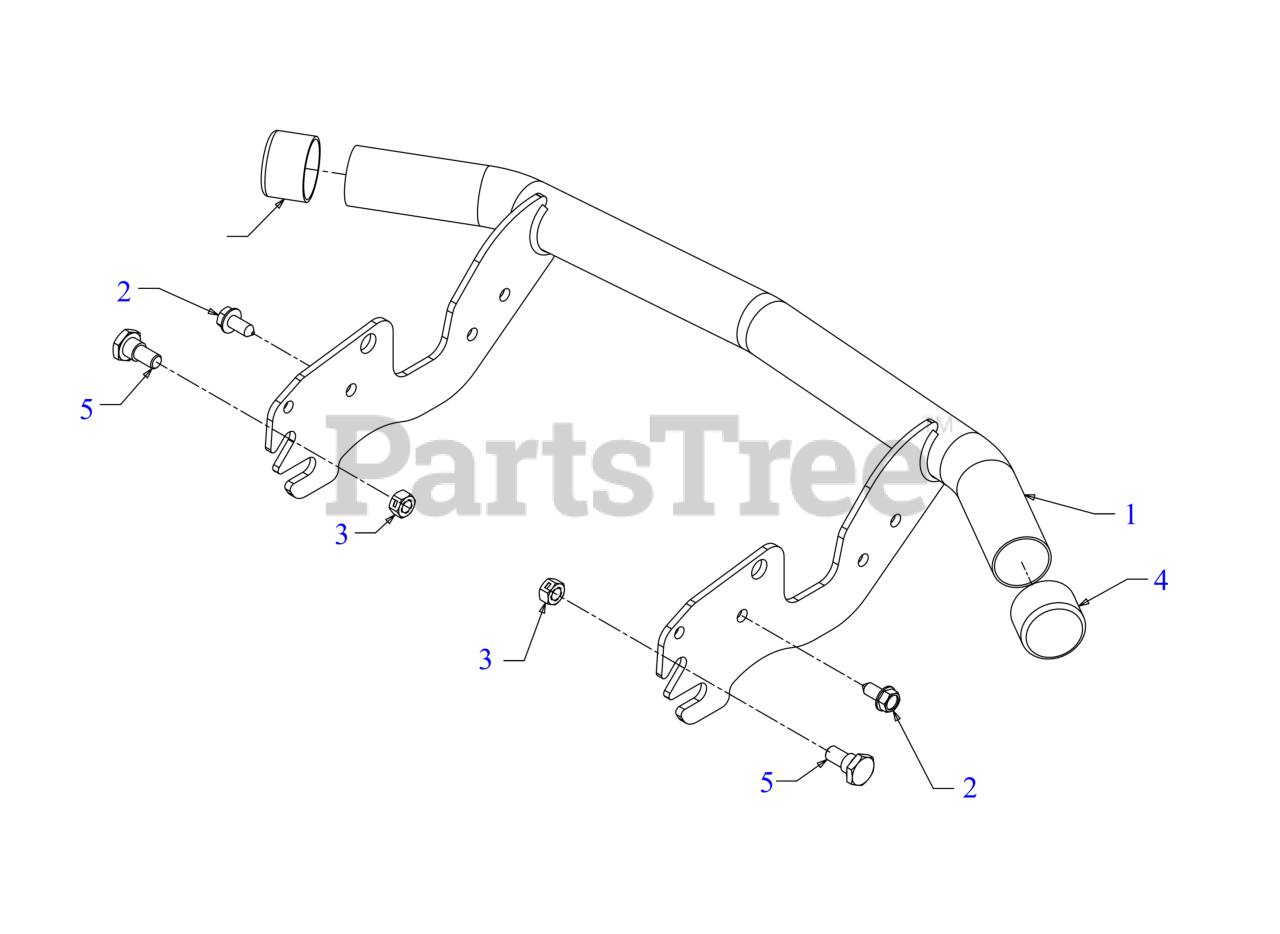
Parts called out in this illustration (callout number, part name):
2	SCREW 5/16-18 x .750
3	LOCK NUT 3/8-16
4	BUMPER CAP
5	SHOULDER SCREW .498 DIA x .340
